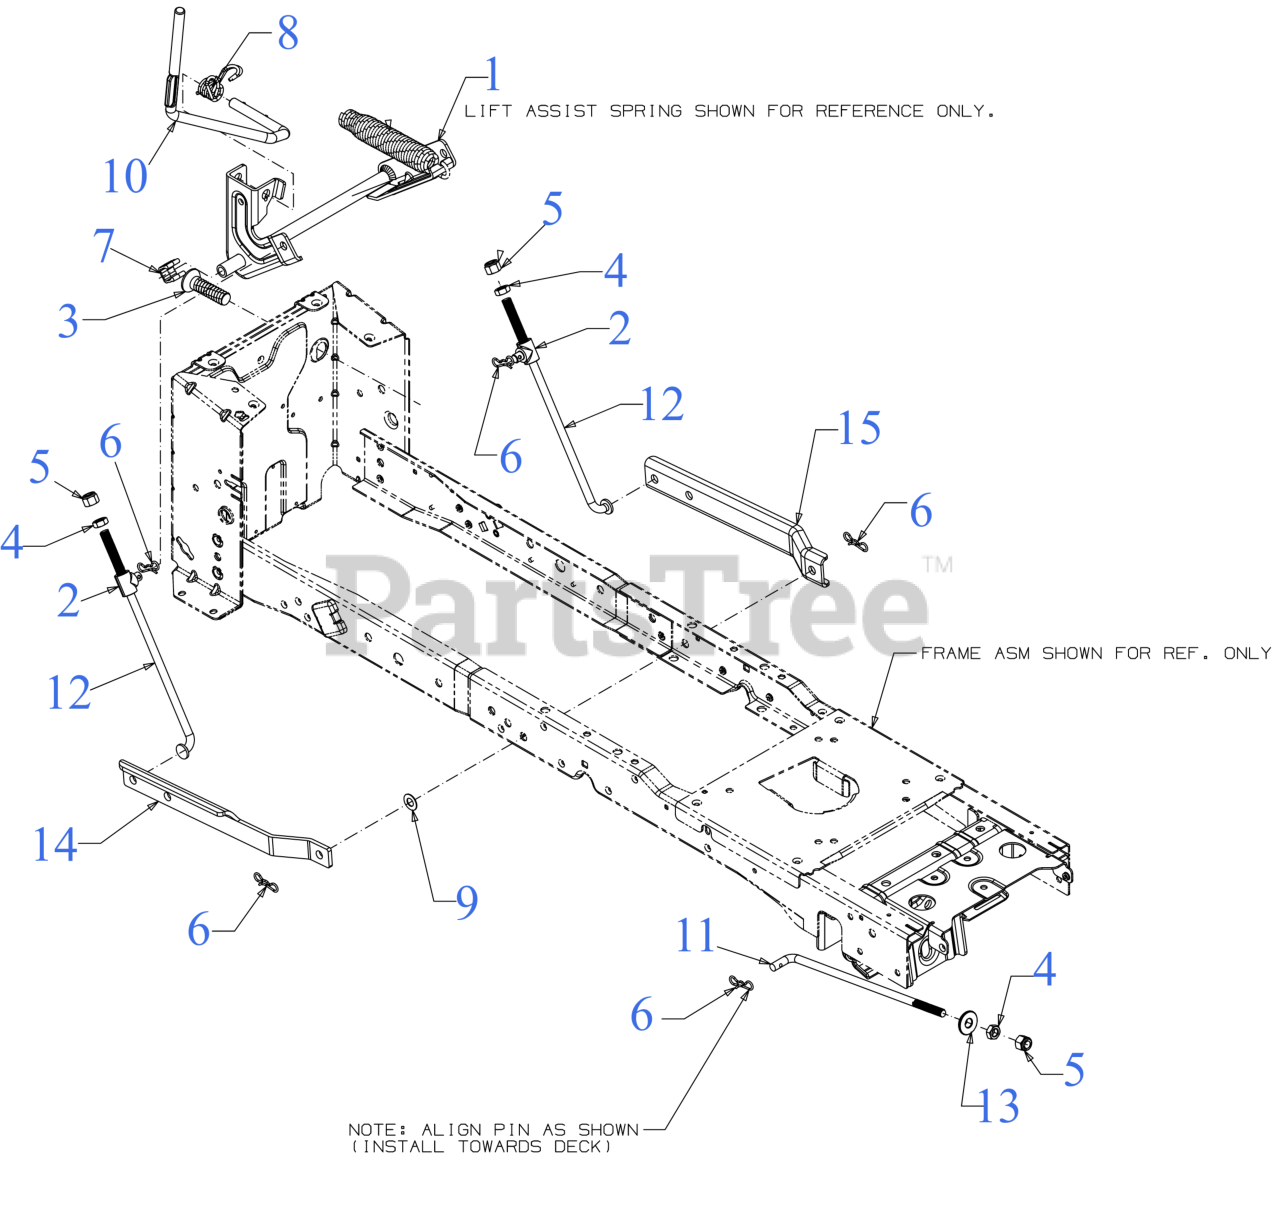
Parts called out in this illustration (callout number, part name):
1	LIFT SHAFT ASSEMBLY
2	LIFT ROD FERRULE
3	LIFT SPRING INSERT
5	HEX LOCK NUT NYLON
6	BOW TIE COTTER PIN
7	SPACER-LIFT SHAFT
8	TORSION SPRING
9	FLAT WASHER .508X1.000X.040
10	DECK LIFT HANDLE
11	DECK FRONT LIFT ROD
12	ADJUSTMENT LIFT ROD
13	DECK LIFT PIVOT CUP
14	LIFT ARM (REAR)
15	LIFT LINK
